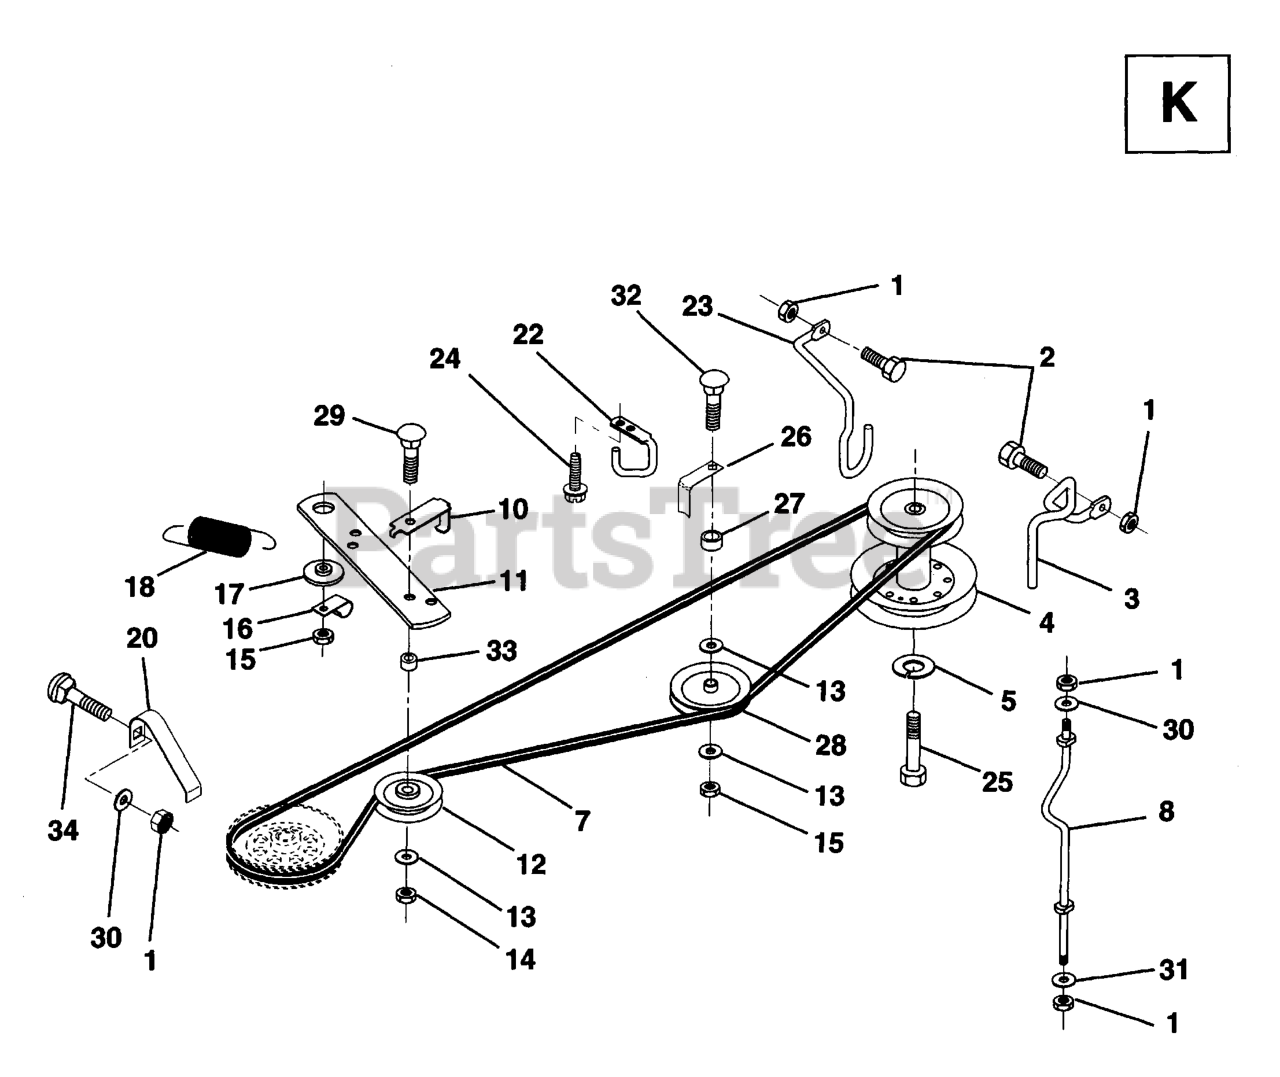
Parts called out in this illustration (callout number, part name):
1	NUT.71038.31-18.HEX.NYLOCK
2	BOLT
3	BELT GUIDE
4	PULLEY.ENGINE.36/38 LR
5	LOCKWASHER
7	V-BELT 77.75
10	KEEPER, BELT
11	ARM/GROUND DRIVE CLUTCH
12	PULLEY.IDLER.FLAT
13	WASHER
14	LOCKNUT
16	CLIP,INSULATOR
17	SPACER RETAINER
18	SPRING.EXTENSION
20	KEEPER, BELT
22	KEEPER,FRA DR BEL
23	KEEPER-MOWER DRIVE LH
24	SCREW
25	Bolt, Hex Hd. 7/16-20 UNF Grade 5
26	KEEPER, BELT
28	PULLEY.IDLER.V.
29	BOLT
30	WASHER
31	WASHER M
33	SPACER NLA
34	RP BOLT 5/16-18 X3/4 ZN/YEL GR
